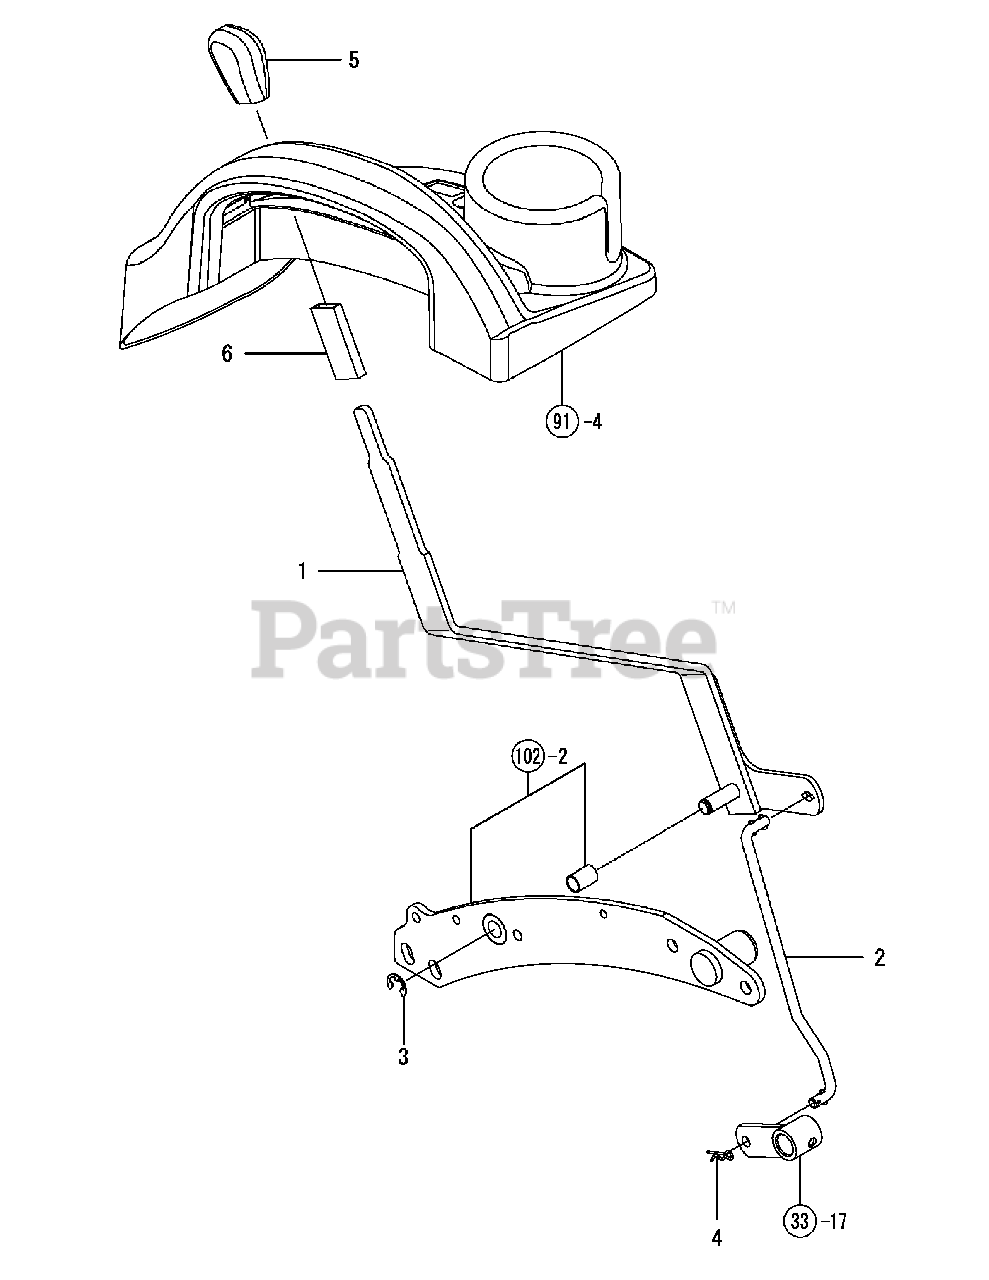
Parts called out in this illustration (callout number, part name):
1	LEVER CMP, PTO
4	SNAP PIN (JASO 8)
5	KNOB, YELLOW
6	TUBE, PROTECTIVE
